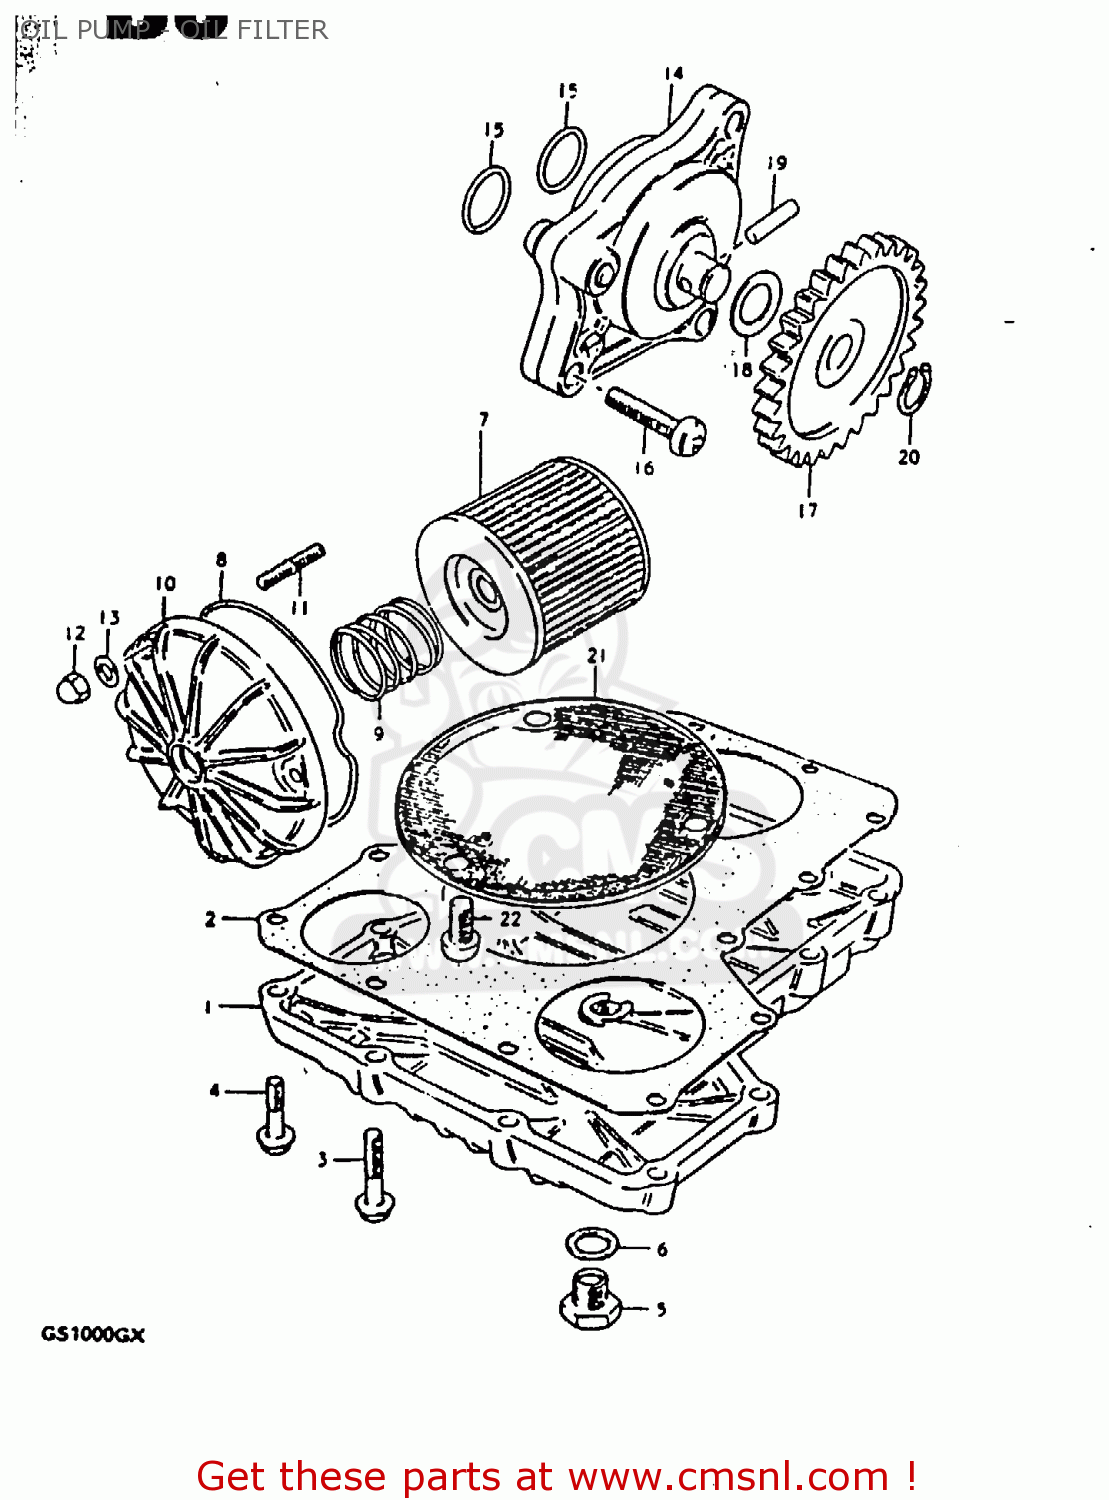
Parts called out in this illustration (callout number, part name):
1	PAN,OIL
2	GASKET,OIL PAN (MCA)
3	BOLT
4	BOLT
5	PLUG
6	GASKET(14X19.2X2) (NAS)
7	ENGINE OIL FILTER SET
8	O RING,OIL FILTER CHAMBER CAP
9	SPRING
10	CAP,ENGINE OIL FILTER
11	STUD 6X20
12	NUT
13	WASHER
14	PUMP ASSEMBLY,OIL
15	O RING(D:1.9,ID:13)
16	SCREW
17	GEAR,OIL PUMP DRIVEN
18	SHIM
19	PIN(4X15.8)
20	CIRCLIP
21	STRAINER,ENGINE OIL
22	SCREW 6X12
